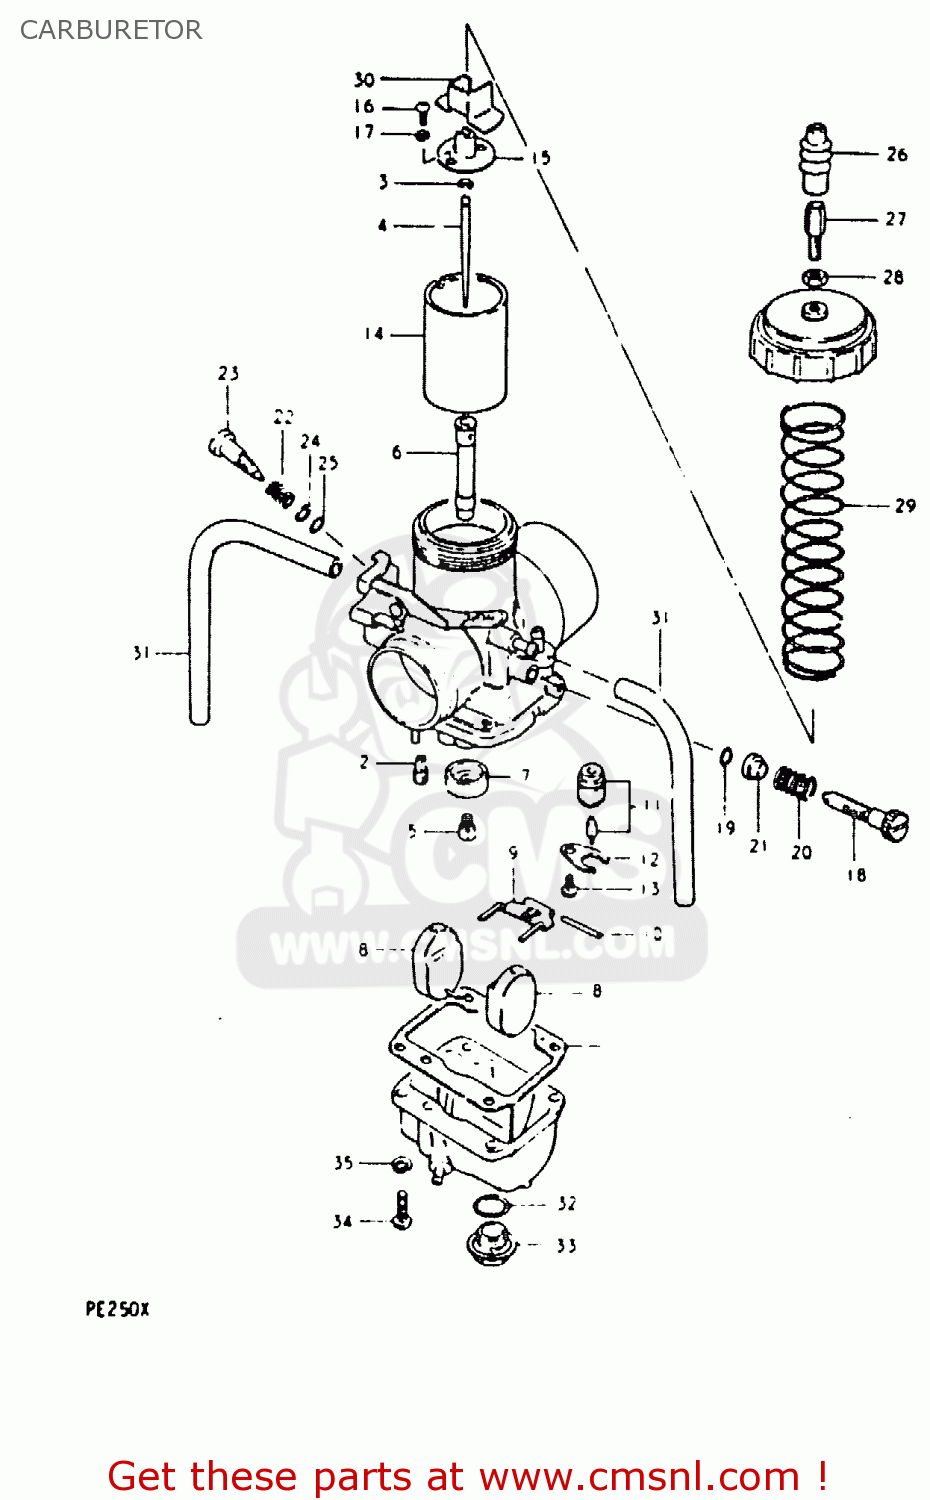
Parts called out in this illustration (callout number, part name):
1	GASKET,FLOAT CAHMBER (NAS)
2	JET,PILOT
3	CLIP
4	NEEDLE JET
5	JET
6	JET,NEEDLE
7	RING,MAIN JET FIXING
8	FLOAT
9	ARM,FLOAT
10	PIN,FLOAT
11	VALVE ASSEMBLY,NEEDLE
12	PLATE
13	SCREW
14	VALVE,THROTTLE
15	CONNECTOR
16	SCREW
17	LOCK WASHER
18	SCREW,THROTTLE STOP
19	O-RING
20	SPRING,THROTTLE STOP
21	COVER
22	SPRING
23	SCREW,PILOT AIR
24	WASHER,PILOT AIR SCREW
25	O RING
26	CAP,CABLE ADJUSTER
27	ADJUSTER,CABLE
28	NUT
29	SPRING,THROTTLE VALVE RETURN
30	COVER,HOLDER
31	HOSE
32	O-RING
33	PLUG
34	SCREW
35	LOCK WASHER
36	JET
